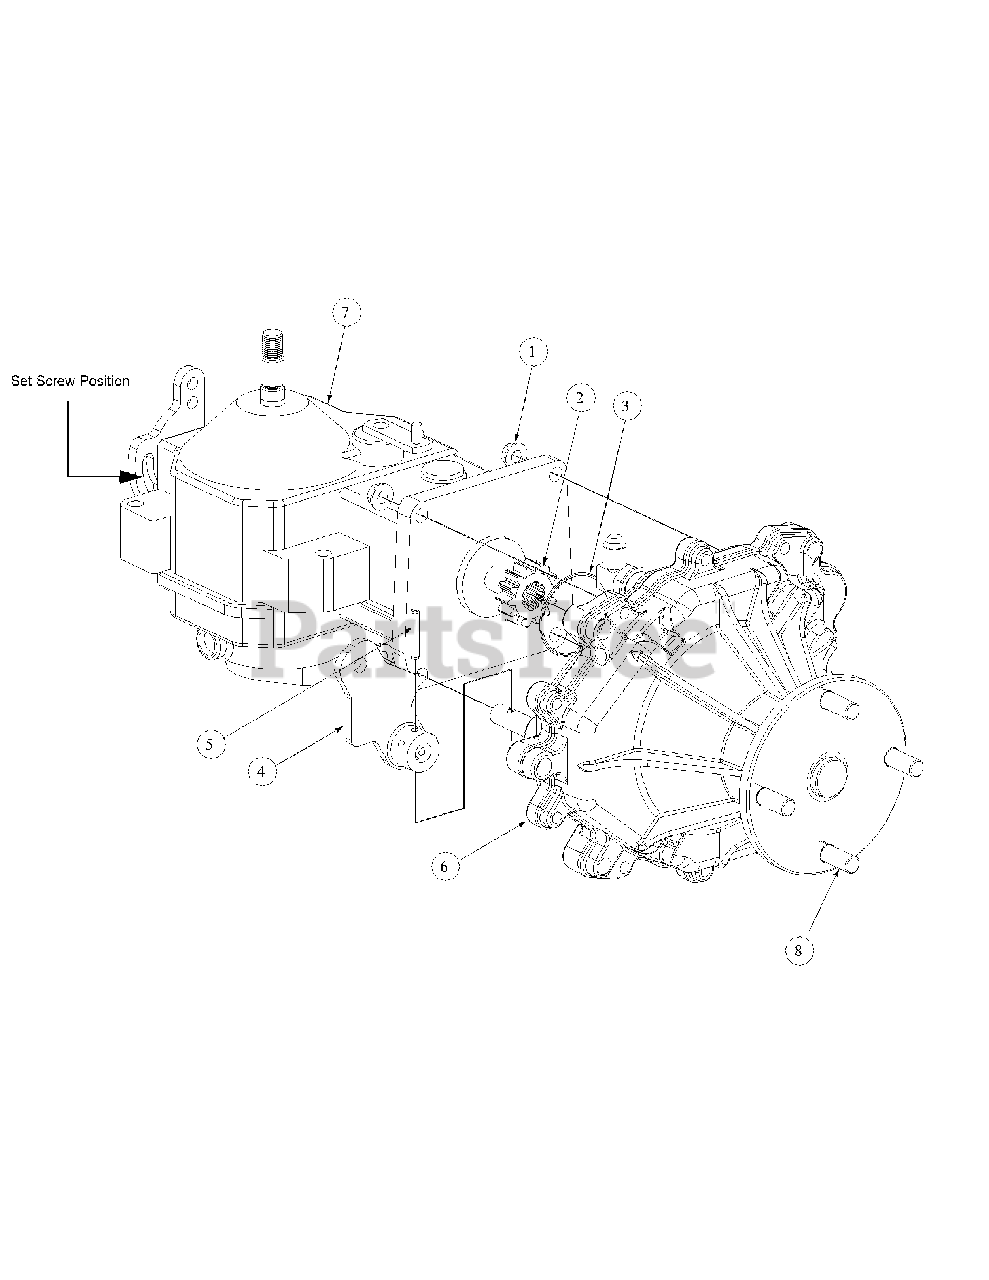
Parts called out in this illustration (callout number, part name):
1	Hex Flange, Lock Nut, 5/16-18
2	Gear, Spur, 14T
3	O-Ring, 2.00 x .070
4	Parking Brake Lever
5	Pin, Spirol, 3/16 x 1.25 HD
6	Transmission Assembly
8	Rib Neck Stud, 1/2-20
9	Set Screw, 5/16 - 24 x 1.25
